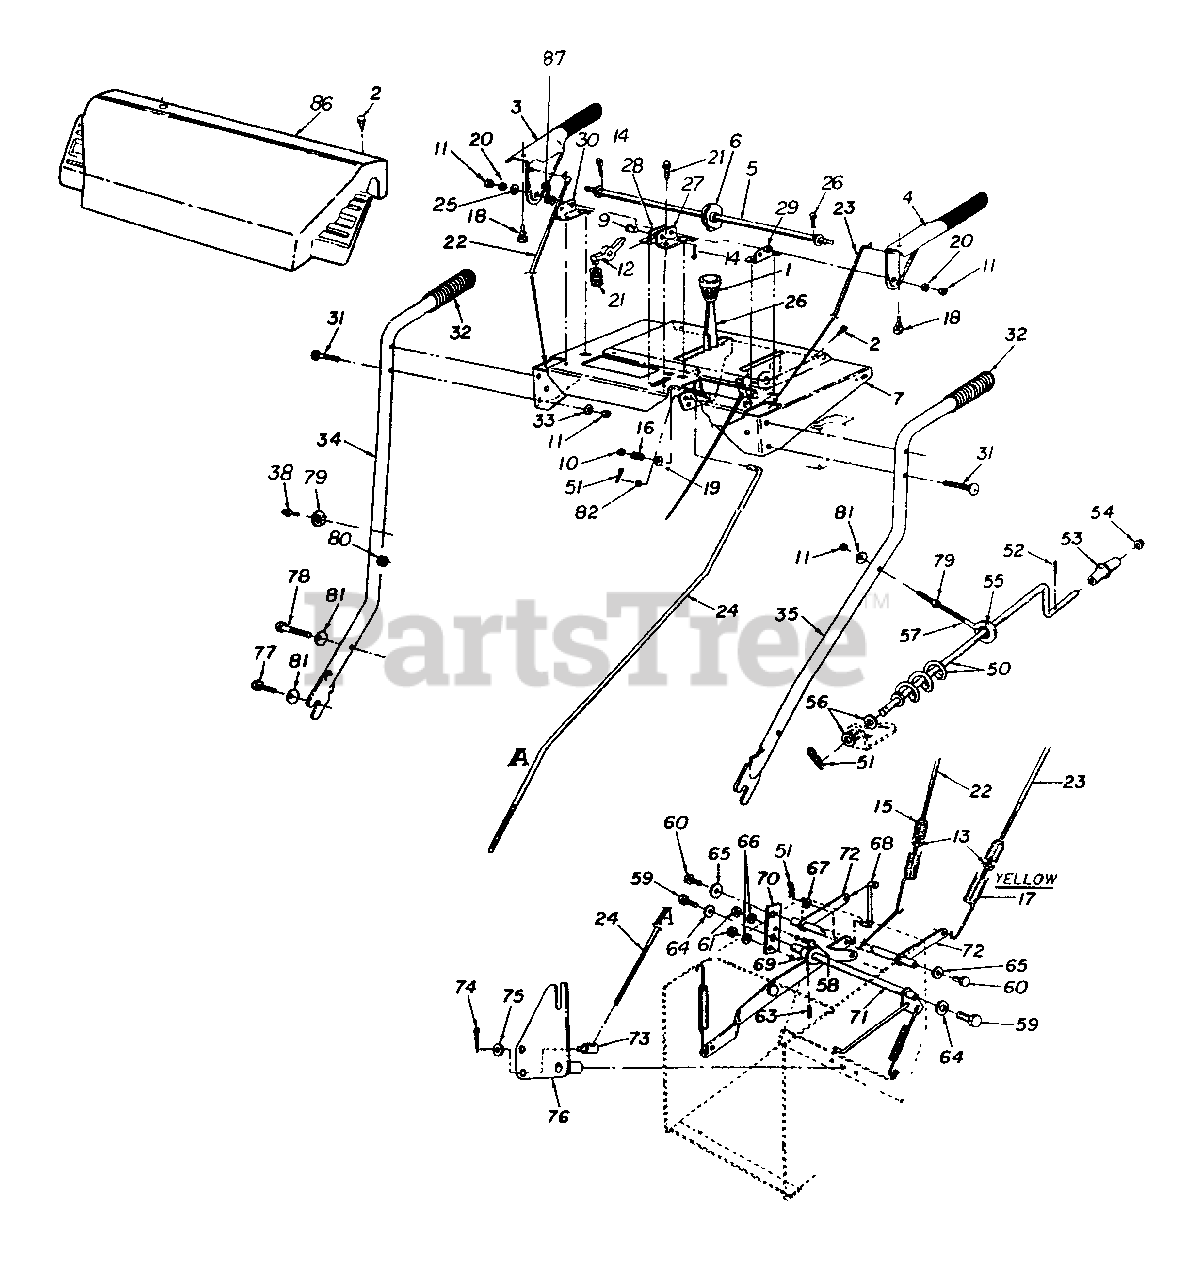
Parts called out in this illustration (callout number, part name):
1	Ball Knob
2	Truss Mach. B-Tap Scr. #10 x .50
3	Engagement Handle R.H. - Black
4	Engagement Handle L.H. - Black
5	Cam Rod
6	Clutch Lock Cam
7	Handle Panel Support Ass'y.
9	Clevis Pin .81 Dia. x 1.0" Lg.
10	Hex Nut 3/8-24
11	Hex Nut 5/16-18
12	Cam Lock Pawl
13	Hex Ins. Lock Nut 1/4-20
14	Cotter Pin 3/32 Dia. x 1.00" Lg.
15	Extension Spring
16	Compression Spring .38" I.D. x .88" Lg.
17	Extension Spring .75" O.D. x .5" Lg.
18	Rubber Bumper
19	Bell-Wash. .400" I.D. x .88" O.D. x .06
20	L-Wash. 5/16" I.D.
21	Wave Spring Washer
22	Lockout Cable x 28" Lg.
23	Lockout Cable x 25" Lg.
24	Shift Rod 34.25" Lg.
25	Washer (Special)
26	Shift Lever
27	L.H. Handle Support Brkt. 5/8"
28	R.H. Handle Support Brkt. 5/8"
29	L.H. Handle Support Brkt. 3/8"
30	R.H. Handle Support Brkt. 3/8"
31	Carriage Bolt 5/16-18 x 1.75" Lg.
32	Grip
33	Bell-Wash. .400" I.D. x .88" O.D. x .06"
52	Serrated Pin
54	Cap Speed Nut 3/8" Rod
55	Grommet
56	Flat Wash 385" I.D. x 62" O.D. x .06
57	Eyebolt Chute Crank
58	Hex Screw 1/4-20 x .62"
59	Hex L-Bolt 5/16-18 x .62"
60	Hex Scr 1/4-20 x .50 w/Patch
61	Hex Nut 1/4-20
63	Roll Pin 3/16 x 1.25
64	Flat Wash .344" I.D. x .875" O.D.
65	Flat Wash .25" I.D. x .93" O.D. x .125
66	L-Wash 1/4" I.D.
67	Fl-Wash .281" I.D. x .62" O.D. x .051
68	"L" Rod .25" Dia. x 4.70" Lg.
69	Drive Clutch Brkt. .627 R.H. Ass'y.
70	Pivot Bracket .63 Hole
71	Drive Clutch Shaft Ass'y.
72	Pivot Cross Shaft Ass'y.
73	Adjustment Ferrule
74	Cotter Pin 3/32 x .75
75	Fl-Wash .344" I.D. x .625" O.D. x .063
78	Hex Screw 3/8-16 x 1.75
81	Bell-Wash .400" I.D. x .88" O.D. x .06"
82	Fl-Wash .344" I.D. x .625" O.D. x .063"
86	Handle Panel
87	Torsion Spring
